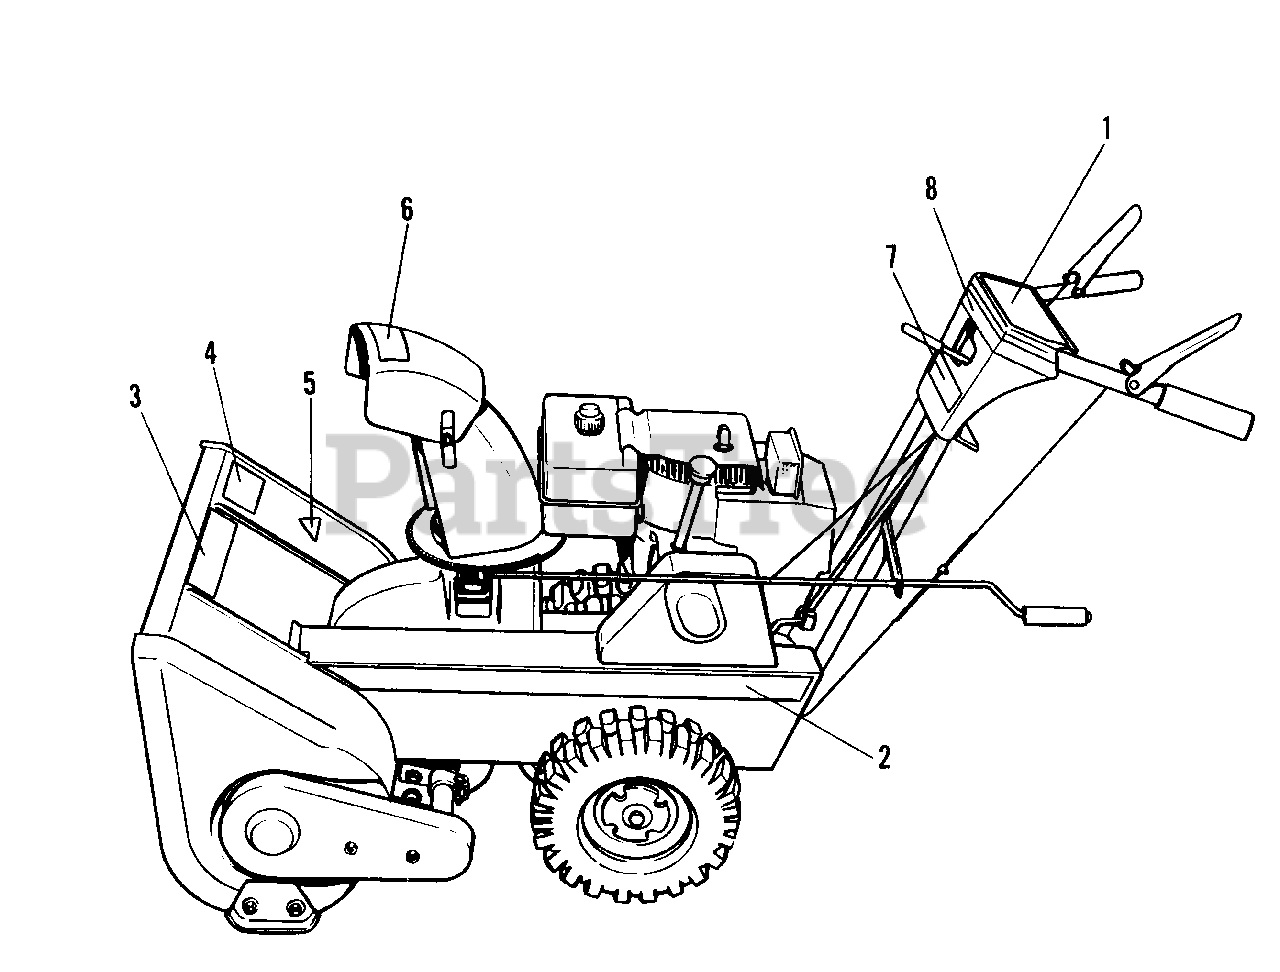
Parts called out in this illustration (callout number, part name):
1	DECAL, Dash
2	DECAL, Snowbuster 524
2	DECAL, Snowbuster 724
2	DECAL, Snowbuster 828
2	DECAL, Snowbuster 1028
3	DECAL, Simplicity
4	DECAL, Warning, Housing
5	DECAL, OPEI
6	DECAL, Warning, Chute
7	DECAL, Simplicity
8	DECAL, Control Cover
